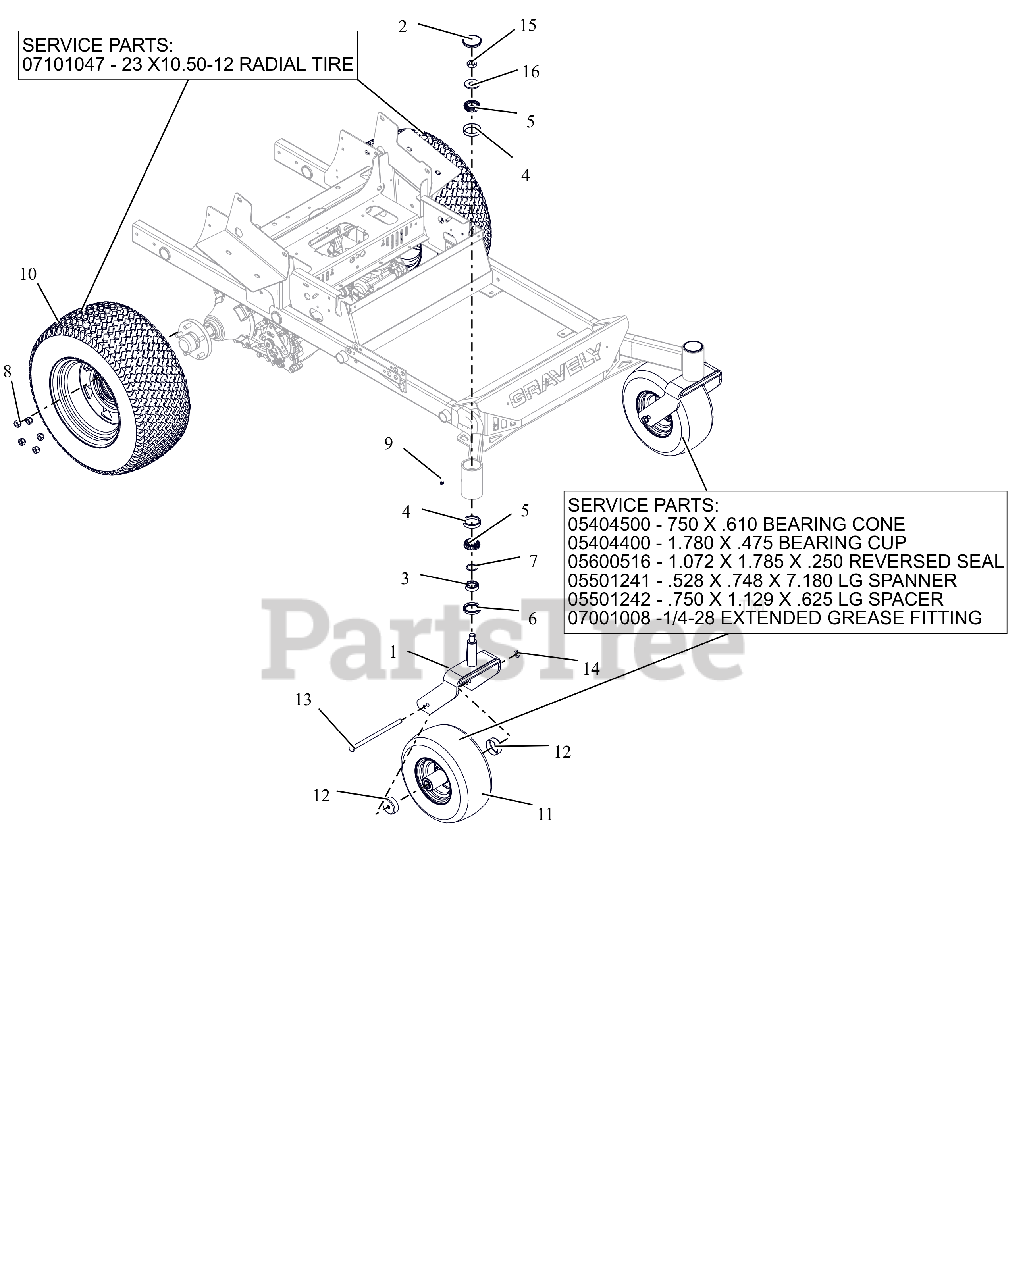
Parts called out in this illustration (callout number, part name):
1	CASTER FORK WMT - RED
2	CAP, DUST
3	SPCR, FRONT CASTER FORK
4	BRG-CUP 2.328X.465
5	BRG-CONE 1.25X.66
6	SEAL, OIL 1.75 X 2.332 X .312
8	NUT, WHEEL .50-20 ZCC
9	FTG, .25-28 FLUSH MNT GREASE
10	ASM,WHL/TIRE 23X10.50-12RADIAL
10	TIRE, 23 X 10.50-12 RADIAL
11	ASM, WHL/TIRE 15X6.00-6 SEMI
11	BRG-CONE .750X.61
11	BRG-CUP 1.781X.475
11	SEAL,1.072X1.785X.250 REVERSED
11	SPANNER, .528X.748X7.18 LG
11	SPACER, .750X1.129X.625 LG
11	GREASE FITTING 1/4-28 EXTENDED
12	SHIELD, WHEEL BEARING
13	BLT, HEX .50-13X9.00 G5 ZCC
14	NUT-LK-TOP-FLG .500-13 GF ZCC
15	NUT, JAM-TOPLOCK .750-16 ZCC
16	WSHR-FL-STL 0.812X2X0.148 ZCC
